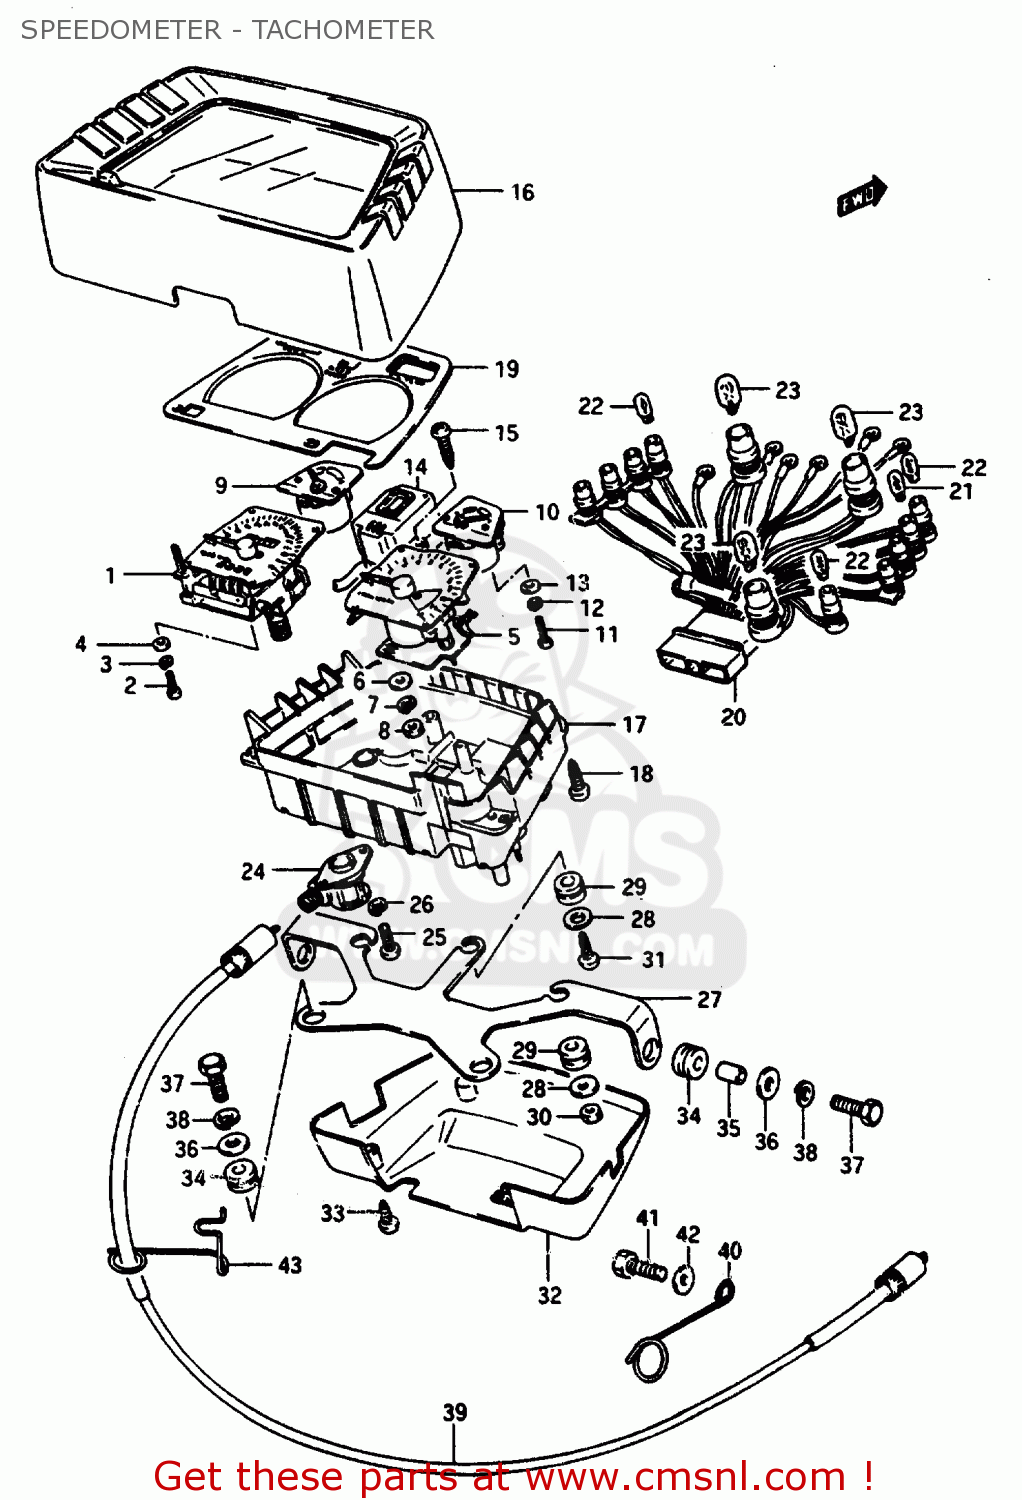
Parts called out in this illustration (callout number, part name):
1	SPEEDOMETER (KILO)
2	SCREW
3	LOCK WASHER
4	WASHER 3.3X8X0
5	TACHOMETER
6	WASHER
7	LOCK WASHER
8	NUT 4MM
9	METER,FUEL
10	METER,OIL TEMPERATURE
11	SCREW
12	LOCK WASHER
13	WASHER 3.3X8X0
14	INDICATOR ASSEMBLY,GEAR POSITION
15	SCREW
16	HOOD, METER
17	CASE,METER
18	SCREW
19	PLATE,METER WINDOW
20	SOCKET, METER
21	BULB(12V1.7W,WB372,T7)
22	BULB(12V3W,WB371,T7)
23	BULB(12V3.4W,T10,BF175-01450A)
24	GEAR BOX,SPEEDOMETER
25	SCREWM4X0.7X10
26	LOCK WASHER
27	BRACKET,METER
28	WASHER,COMBINATION METER
29	CUSHION
30	NUT 4MM
31	SCREW
32	COVER,METER
33	SCREW
34	CUSHION
35	SPACER (6.1X9X9)
36	WASHER
37	BOLT,M6X1X20
38	WASHER,LOCK
39	CABLE ASSEMBLY,SPEEDOMETER
40	CLAMP,SPEEDOMETER CABLE
41	BOLT, UPPER
42	WASHER
43	GUIDE,METER CABLE
